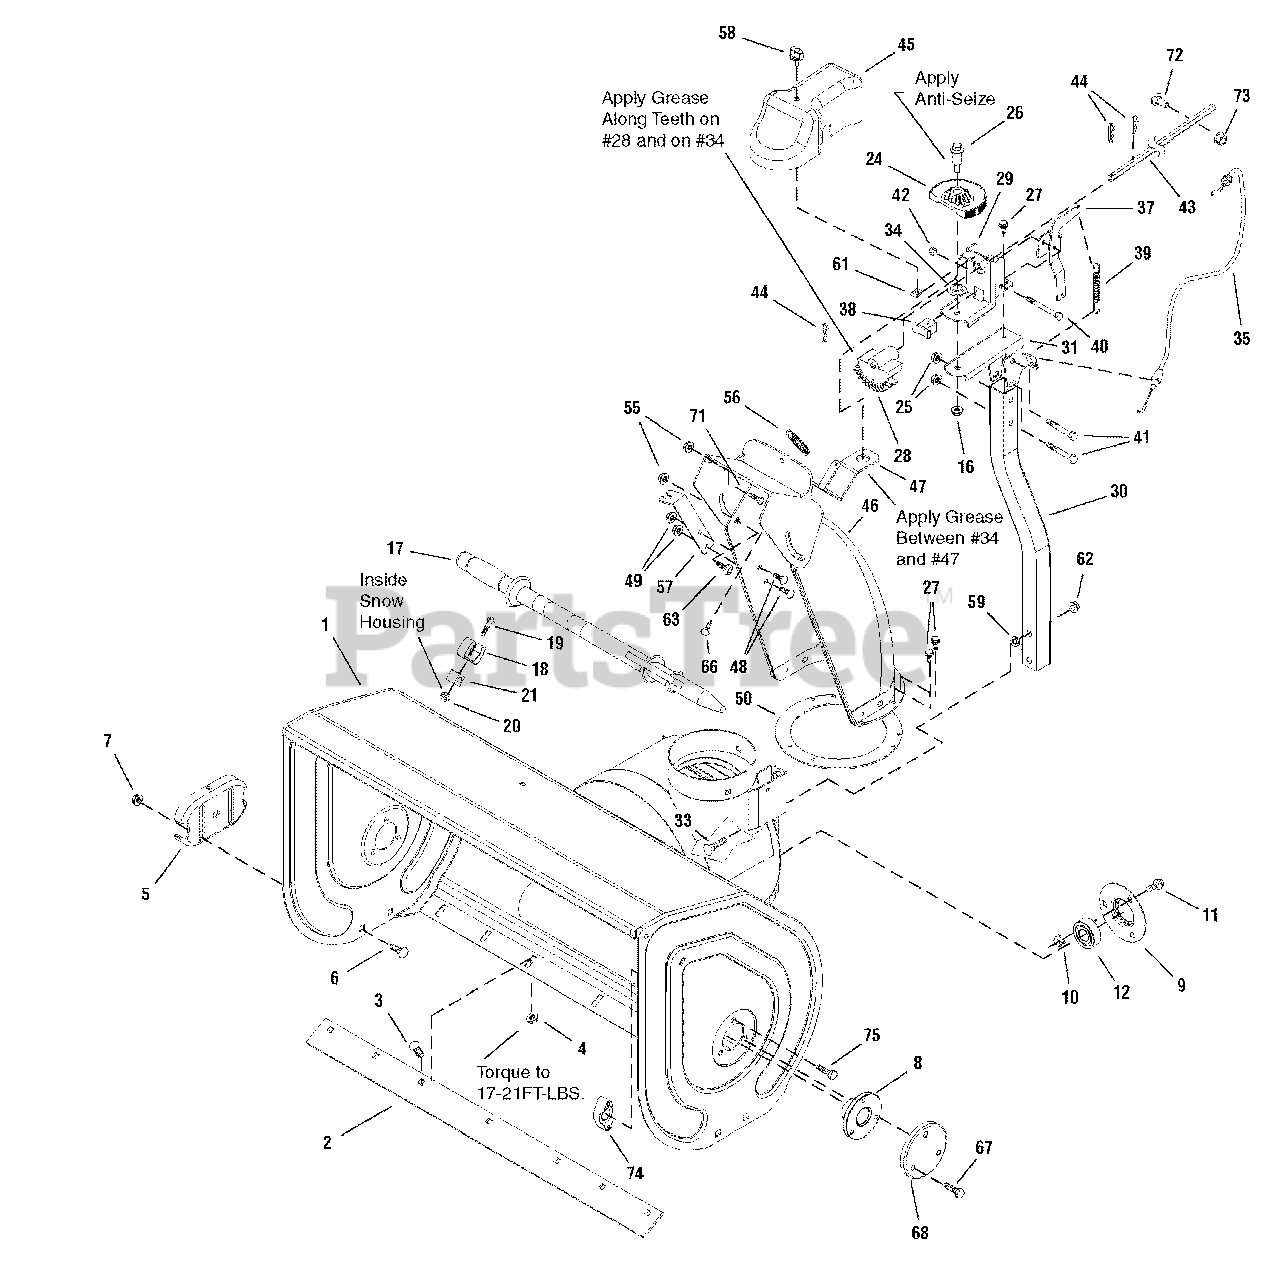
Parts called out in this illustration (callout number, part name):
1	HOUSING ASSEMBLY, 26"
1	HOUSING ASSEMBLY, 28"
2	BLADE, Scraper 26"
2	BLADE, Scraper 28"
3	CARRIAGE BOLT, 5/16-18 x 5/8 G5
4	NUT, Hex Flange 5/16-18 Two-Way Lock
5	SKID, Shoe Reversible
6	CARRIAGE BOLT, 3/8-16 x 3/4 G5
7	NUT, Hex Flange 3/8-16 ESNA
8	BEARING, Flange
9	BEARING, Retainer
10	RETAINER, Nut, 5/16-18
11	SCREW, Hex Whiz Lock Flange 5/16-18 x 3/4
12	BEARING
16	NUT, Hex Flange 5/16-18, Whiz Lock
17	STICK, Cleanout w/Brush
18	CLIP, Retainer
19	CAPSCREW, Hex Washer, #10 x 1-1/4
20	NUT, Hex Lock 10-24 w/Nylon Insert
21	BLOCK, Universal Pivot
24	GEAR, 13 Tooth
25	NUT, Hex Keps Conical Washer, 5/16-18
26	BOLT, Shoulder 5/16-18 x 3/5
27	SCREW, Hex Washer Head Taptite 1/4-20 x 1/2
28	GEAR, Sector 34 Tooth Powdered Metal
29	SUPPORT, Driver Gear
30	TUBE, Support
31	BRACKET, Gear Support
33	CARRIAGE BOLT, 3/8-16 x 1-3/4
34	WASHER, Powdered Metal
35	CABLE, Chute Brake
37	BRACKET, Brake
38	ARM & PAD ASSEMBLY, Brake
39	SPRING, Extension
40	CAPSCREW, Hex Head 1/4-20 x 2-1/2 G5
41	CAPSCREW, Hex Head 5/16-18 x 1-3/4
42	NUT, Hex Centerlock 1/4-20
43	ROD, Hex Chute
44	PIN, Quick
45	COVER, Chute
46	CHUTE & DEFLECTOR ASSEMBLY
47	BRACKET, Chute Support
48	CARRIAGE BOLT, 1/4-20 x 5/8 G5
49	NUT, Hex Flange 1/4-20 Whiz Lock
50	RING, Chute Base
55	NUT, Hex Flange 5/16-18 ESNA
56	SPRING, Extension
57	BRACKET, Cable
58	KNOB & SCREW ASSEMBLY
59	NUT, Push Pal 3/8
61	NUT, Retainer Speed #10-24 w/Extrusion
62	NUT, Hex Keps Conical Washer 3/8-16
63	SCREW, Truss Head Trox Drive 5/16-18 x 3/4
66	SCREW, Pan Head Self Tap Torx 5/16-18 x 1/2
67	SCREW, Hex Washer head Taptite 5/16-18 x 1-1/4
68	COVER, Bushing
71	SCREW, Truss Head Torx 5/16-18 x 7/8
72	BOLT, Carriage, 1/4-20 x 1
73	NUT, Flange, Nylock, 1/4-20
74	BEARING, Auger Shaft
75	SCREW, 5/16-18 x 3/4
